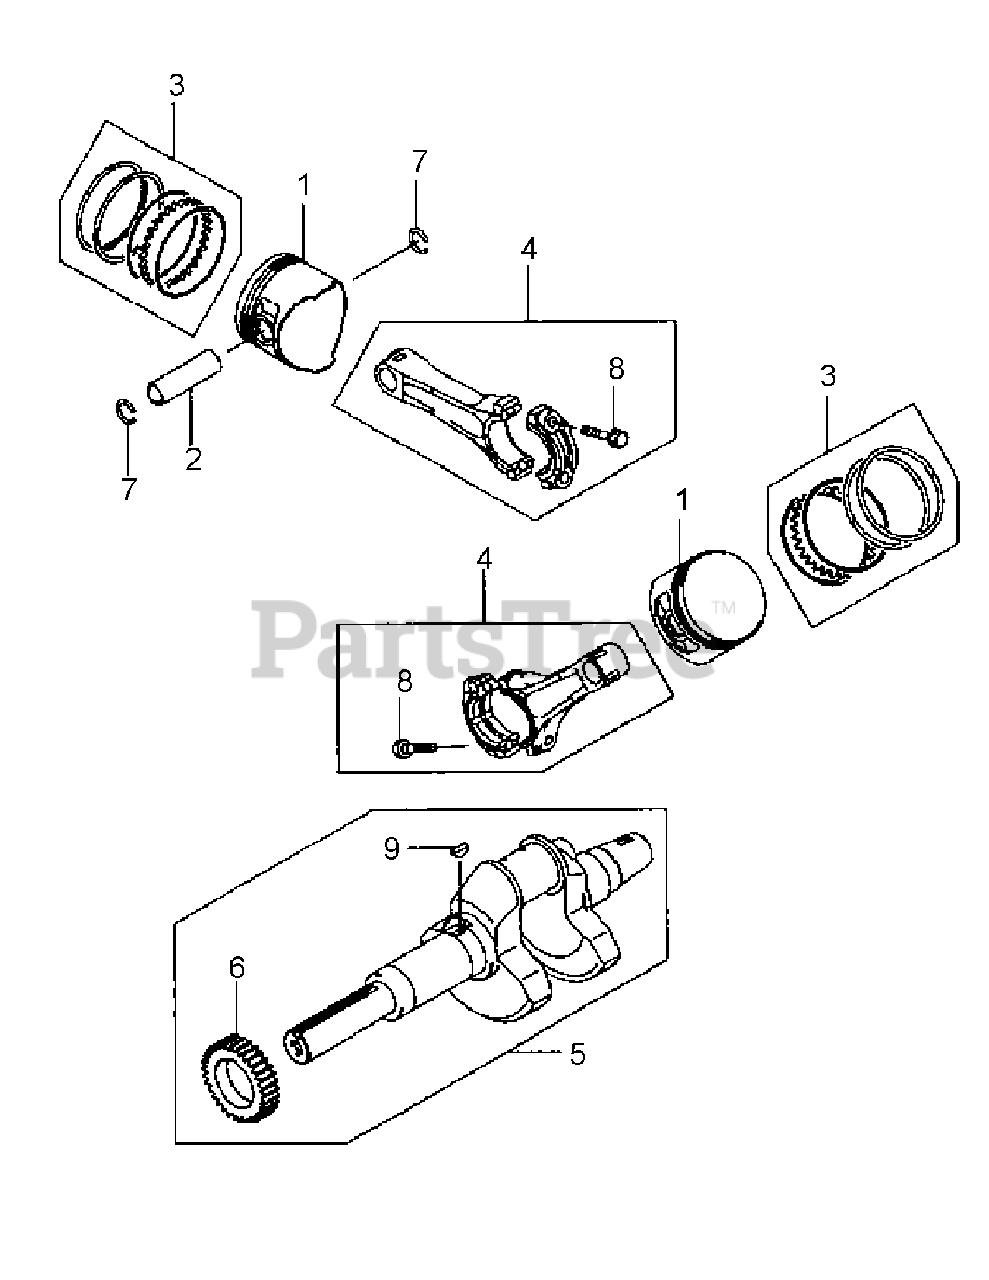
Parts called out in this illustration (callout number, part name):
1	ENGINE PISTON
1	ENGINE PISTON (.50)
3	PISTON RING SET
3	PISTON RING SET (.50)
4	CONNECTING ROD ASSY.
5	CRANKSHAFT ASSY.
6	SPUR GEAR 33T
9	WOODRUFF KEY
